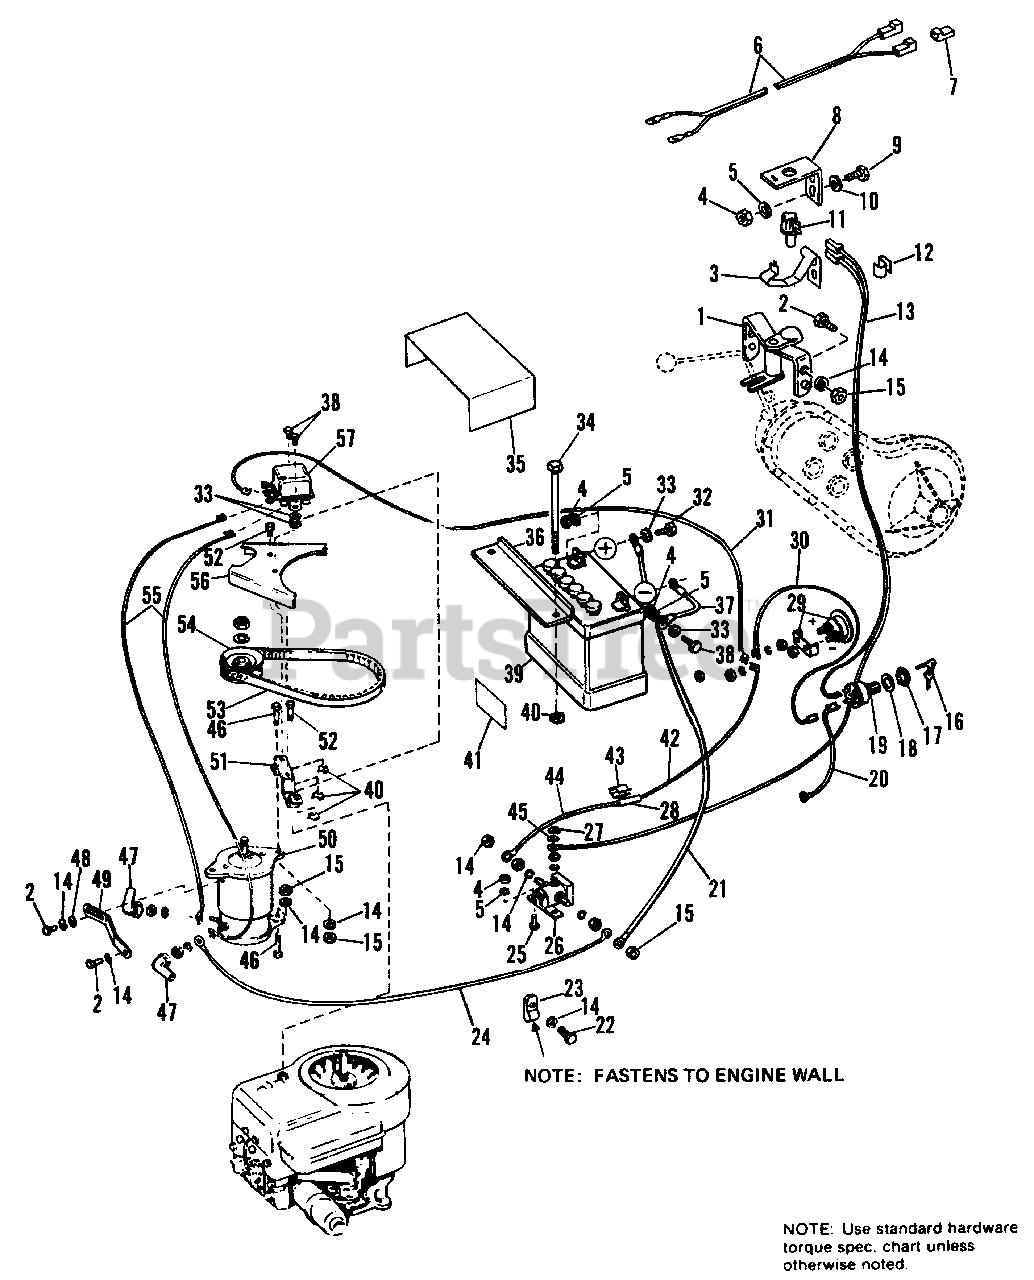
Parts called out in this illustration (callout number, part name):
1	PIVOT ASSY.
2	CAPSCREW, Hex Hd., 5/16-18 x 3/4
3	CLIP, Spring
4	NUT, Hex, Full, 1/4-20 (Qty. 5 on 990904)
5	LOCKWASHER, 1/4 (Qty. 5 on 990904)
6	WIRE (990904 Only)
7	CONNECTOR, Insulated
8	BRACKET (990904 Only)
9	CAPSCREW, Hex Hd., 1/4-20 x 3/4
10	WASHER, Plain, 3/16
11	SWITCH (990904 Only)
12	CLIP, Speed
13	WIRE (990904 Only)
14	LOCKWASHER, 5/16 (Qty. 8 on 990904)
15	NUT, Hex, Full, 5/16-18
17	NUT, Hex, Special
18	LOCKWASHER, 9/16
19	SWITCH, Key
20	WIRE, Switch to Engine Ground
21	CABLE, Battery
22	CAPSCREW, Hex Hd., 5/16-18 x 1/2
24	CABLE, Generator
25	CAPSCREW, Hex Hd., 1/4-20 x 1/2
27	NUT, Hex, Full, #10-32
28	FUSE, 20 amp
29	AMMETER
29	AMMETER (990904 Only)
30	WIRE, Positive
31	WIRE, Battery
32	CAPSCREW, Hex Hd., 3/8-16 x 3/4
33	WASHER, Plain, 1/4
34	CAPSCREW, Hex Hd., 1/4-20 x 7
35	INSULATION, Battery
36	CLAMP, Battery
37	CABLE, Generator to Solenoid
38	CAPSCREW, Hex Hd., 1/4-20 x 3/4
40	NUT, Retainer
41	FILM, Battery
42	WIRE, Negative Ammeter to Solenoid
43	CLIP, Fuse
44	WIRE, Solenoid to Negative
45	LOCKWASHER, Ext., #10
46	CAPSCREW, Hex Hd., 5/16-18 x 1-3/4
47	COVER, Terminal
48	WASHER, Plain, 5/16
49	STRAP, Adjustment
50	MOTOR, Generator
51	BRACKET, Regulator
52	CAPSCREW, Hex Hd., 1/4-20 x 5/8
54	PULLEY, Generator
56	GUARD, Pulley
57	REGULATOR, Voltage
